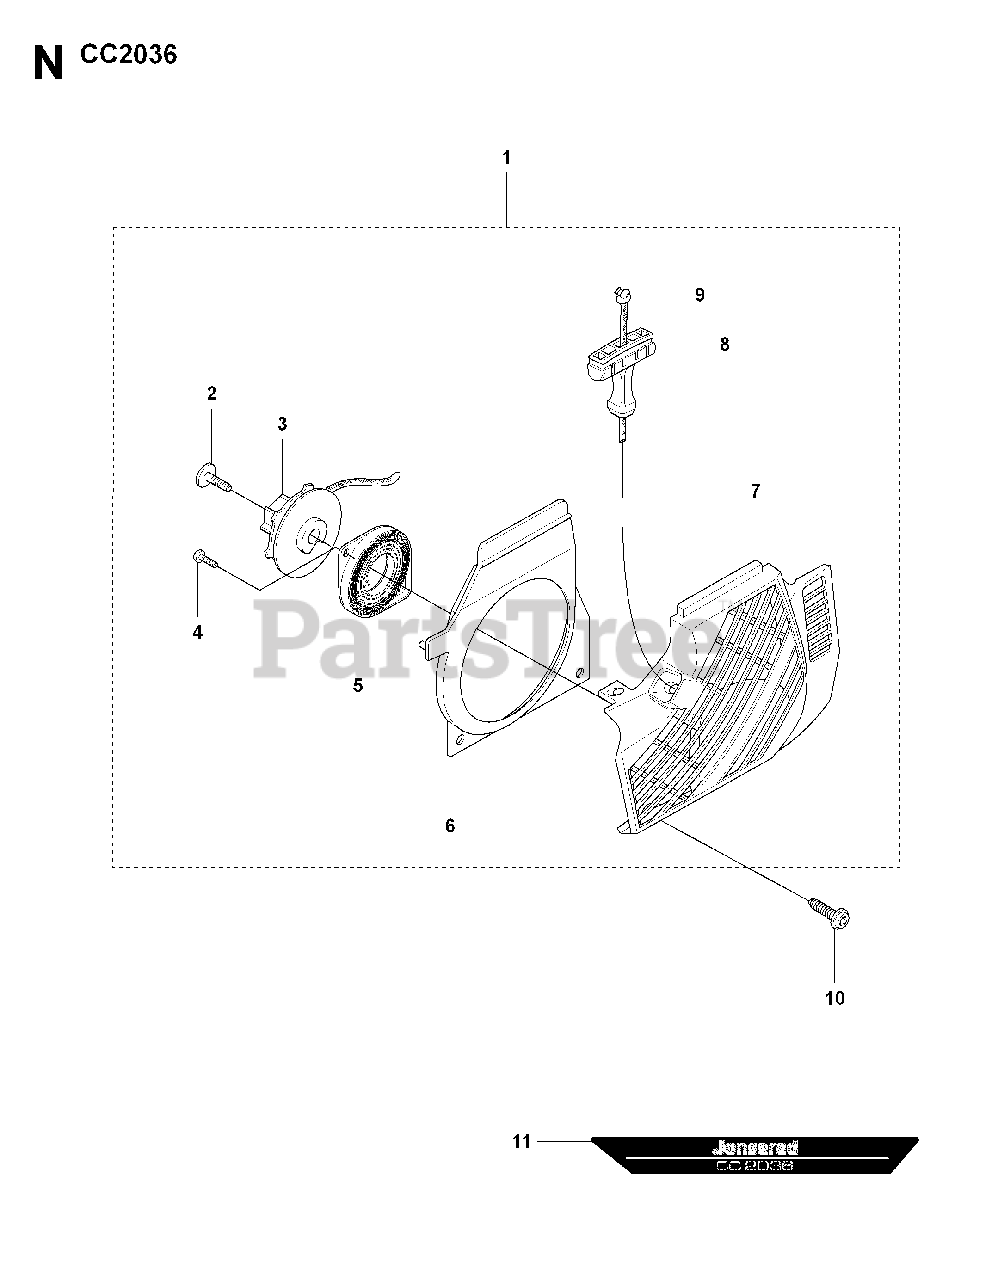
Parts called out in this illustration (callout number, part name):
1	STARTER DEVICE
3	STARTER PULLEY
5	RECOIL SPRING
6	AIR CONDUCTOR
7	STARTER DEVICE
9	STARTER ROPE
